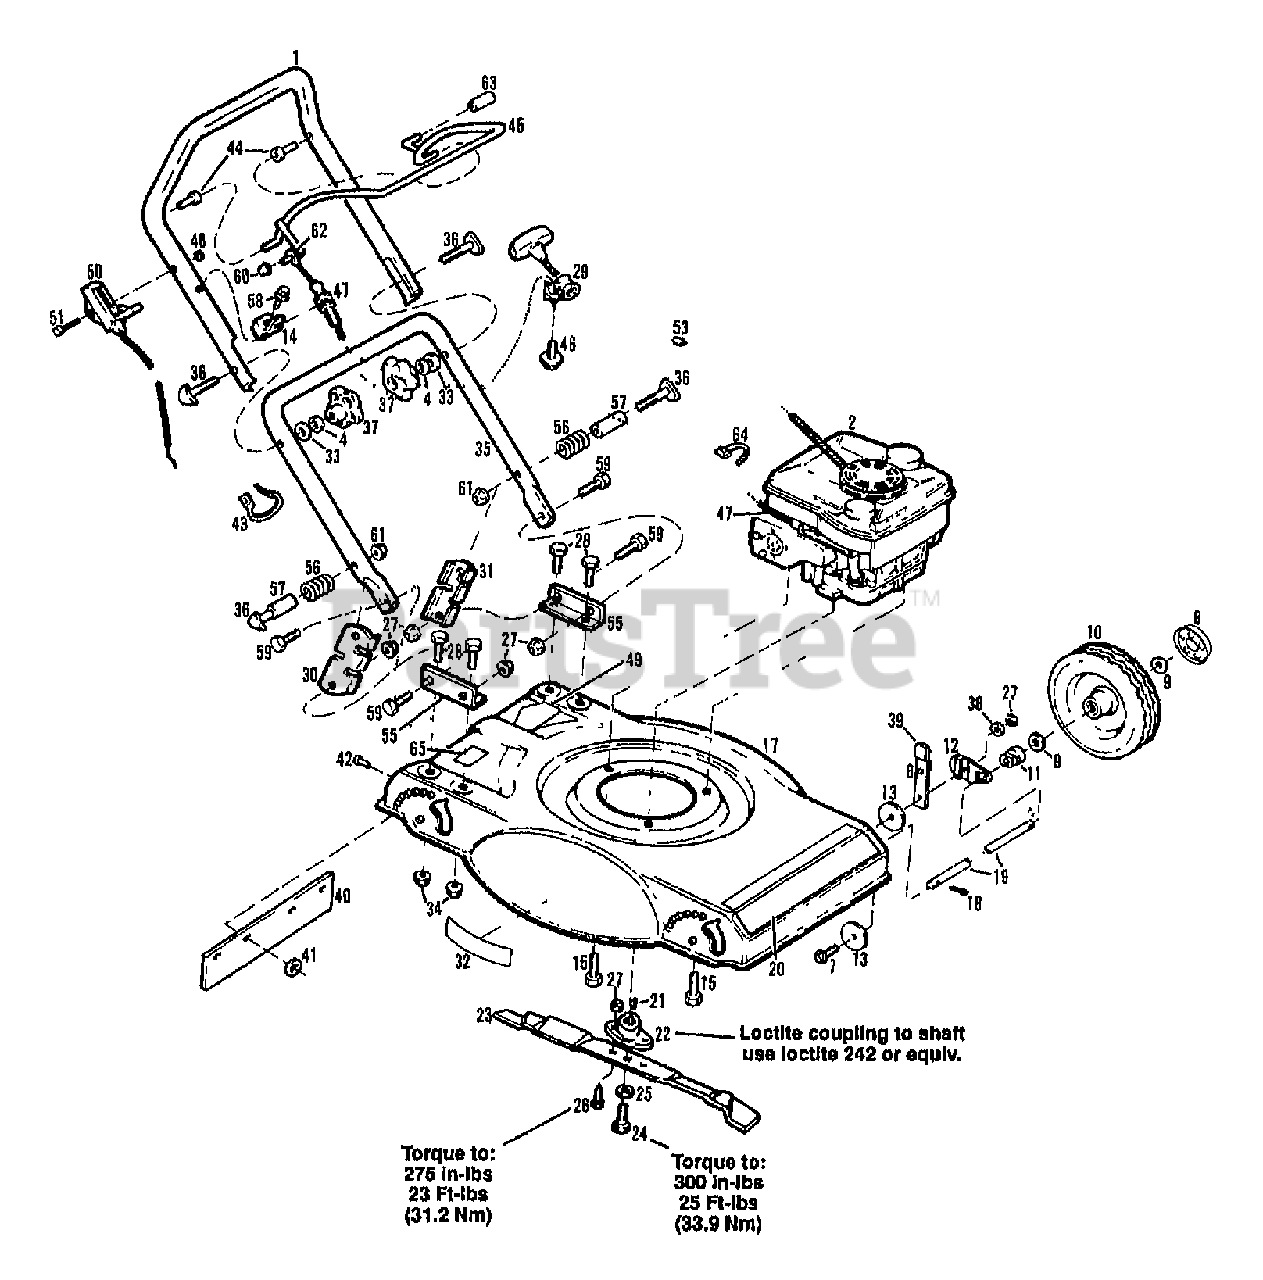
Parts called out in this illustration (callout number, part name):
1	HANDLE-UPPER
2	BRIGGS & STRATTON ENGINE, 121702
4	WASHER-LK .312 ZP
6	ASSM-LEVER HEIGHT ADJUST
7	SCR-HFLK 3/8-16X1.00 ZP
8	CAP-HUB T/B MULCHERS
9	WASHER-FLAT .88X.5X.06 ZP
10	ASSM-TIRE & WHEEL
11	BEARING-AXLE
12	ARM-WHEEL MOUNTING
13	WASHER-1.75X.39X.059
14	BRKT-CONTROL CABLE
15	SCR-HH 3/8-16X1.0 THDFM
17	ASSM-BASE W/DECALS
18	PIN-COTTER .125 X .75 ZP
20	DECAL-LOGO MULCHER 20"
21	KEY-WOODRUFF
22	ASSM-BLADE COUPLING
23	BLADE-CUTTER
24	SCR-SHOULDER
25	WASHER-LK .5
26	SCR-HH 3/8-16X1.0 G5 ZP
27	NUT-LOCK 3/8-16
28	SCR-HFLK 5/16-18X.62 G5ZP
29	GUIDE-ROPE
30	SUPPORT-HANDLE RH
31	SUPPORT-HANDLE LH
32	DECAL-CAUTION
33	WASHER-FLAT 5/16 SAE
34	NUT-HFLK 5/16-18 ZP
35	HANDLE-LOWER
36	SCR-CURVED HD 5/16-18X2.0
38	WASHER-FLAT 3/8 SAE
39	GRIP-VACUCUT
41	WASHER-.88X.2X.059
42	RIVET-POP
43	TIE-CABLE
44	BEARING-FLANGED
45	CONTROL-ENGINE
46	SCR-HFLK 1/4-20X1.0 THFRM
47	ASSM-CABLE
48	NUT-HT LK 1/4-20
49	DECAL-OPEI CAUTION
51	SCR-HH 1/4-20X1.75 G5 ZP
53	STOP-STARTER ROPE
55	BRKT-HANDLEBAR
56	SPRING-COMPRESSION
57	SPACER
58	SCR-FLANGE 1/4-20X3/4 GR5
59	SCR-HH 3/8-16X.75 G5 ZP
60	CAP-PUSH ON .312 DIA
61	NUT-HFT/LK
62	RING-GRIP EXT .312 ID
63	GRIP-HANDLE
64	TIE-CABLE NYLON BLACK
65	DECAL-U.S.A.
